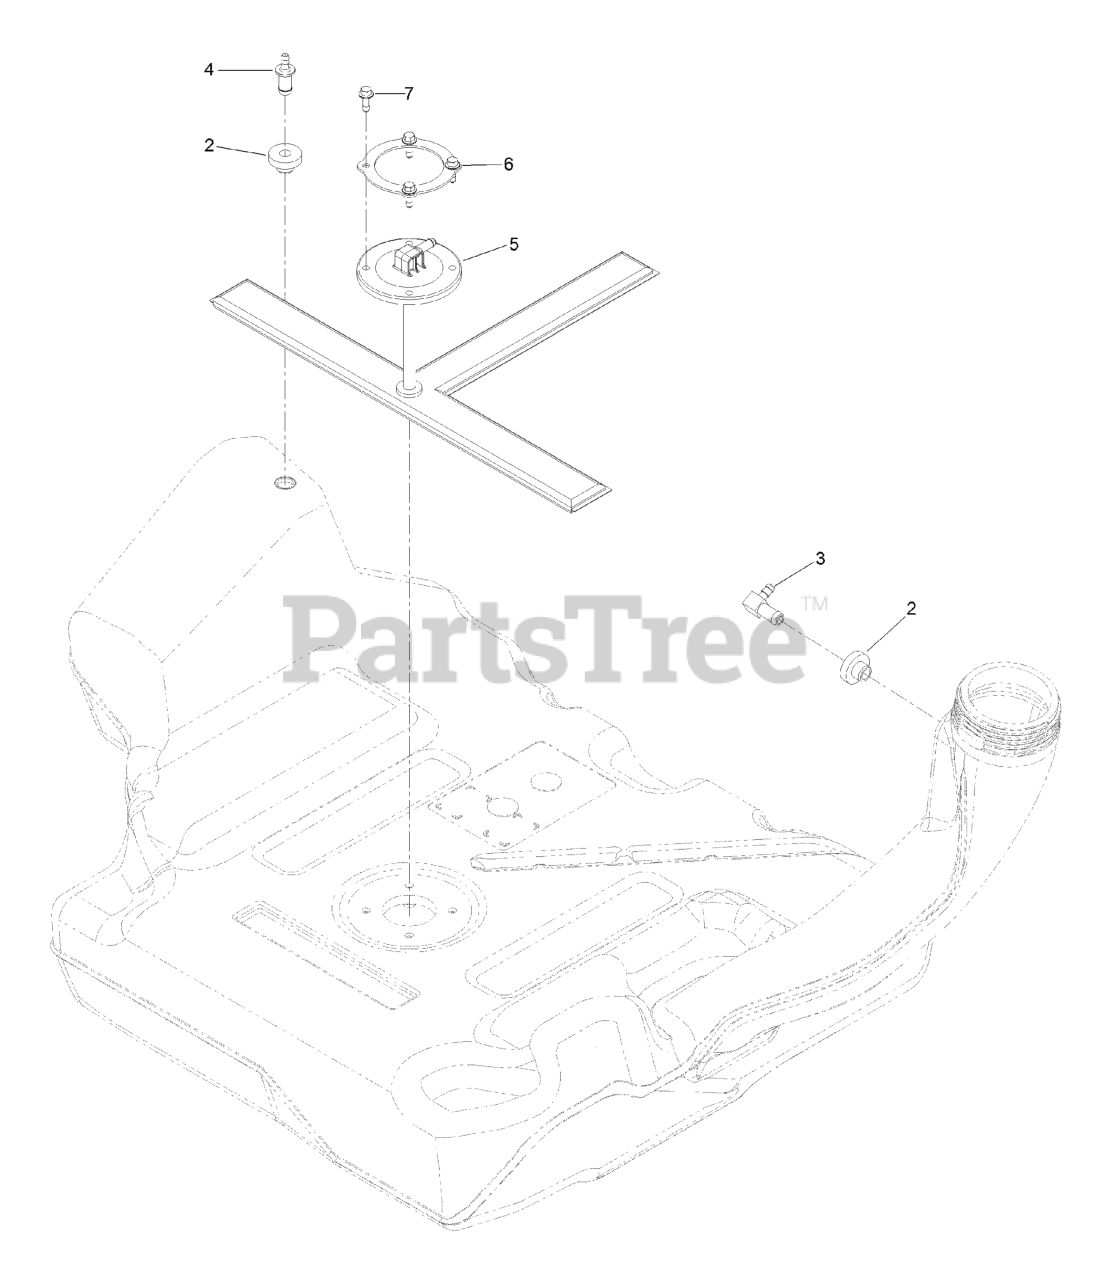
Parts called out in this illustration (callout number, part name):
2	BUSHING
3	FITTING-90 DEG
4	FITTING-ORIFICE, STRAIGHT
5	PICKUP-FUEL
6	RING-RETAINER
